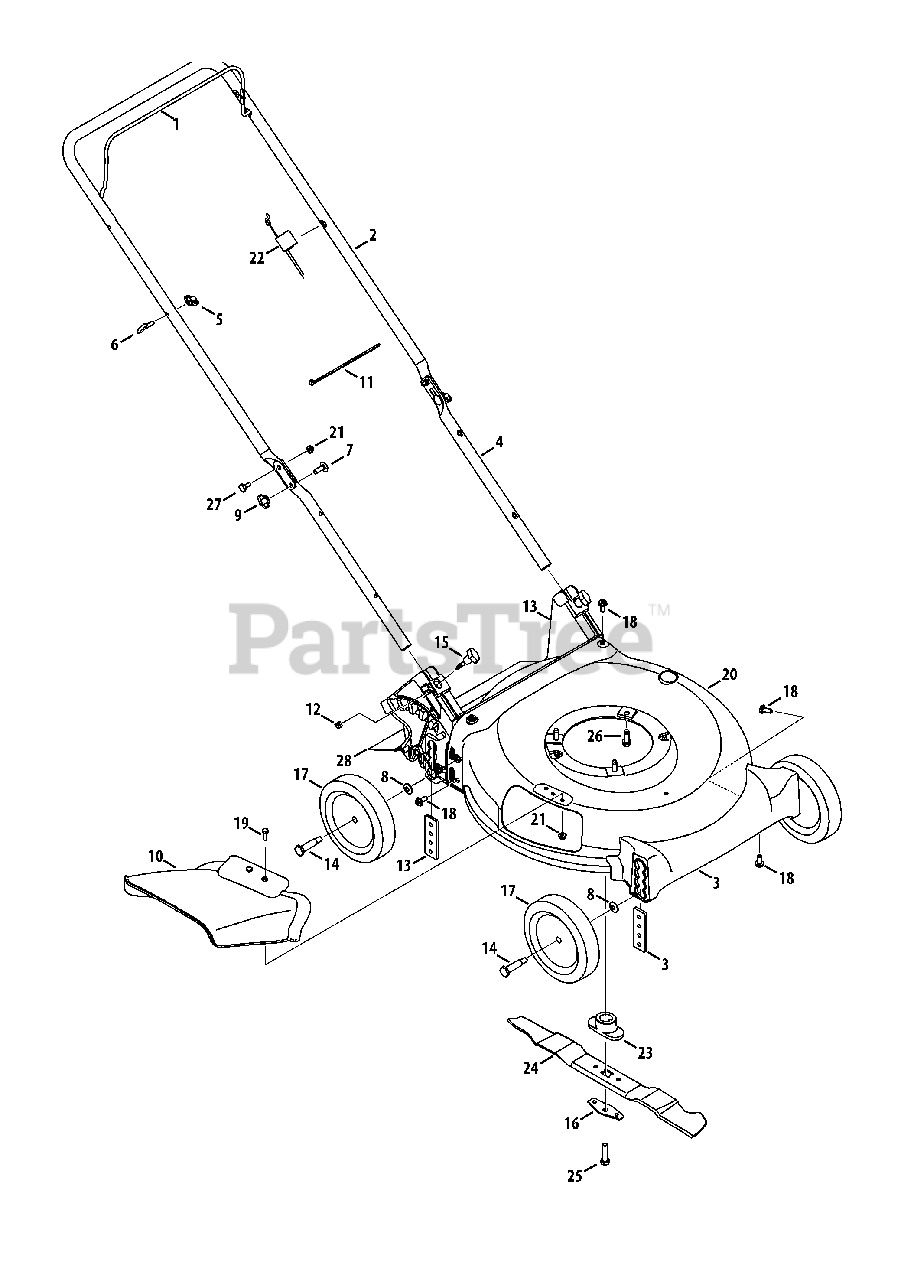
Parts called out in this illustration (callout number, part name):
1	Blade Control
2	Upper Handle
3	Front Cover Assembly
4	Lower Handle
5	Wing Nut
6	Rope Guide
7	Carriage Screw ,5/16-18
8	Washer, .401 x .870 x .060
9	Wing Knob
10	Side Chute
11	Cable Tie
12	Nut, Sq., 1/4-20
13	Rear Baffle
14	Shoulder Screw
15	Wing Nut
16	Blade Bell Support
17	Wheel, 7" Star-Dia., Oys. Gray
18	Screw, 5/16-14 x .750
19	Screw, 1/4-20 x .750
20	Deck , 21"
21	Nut, Flange Lock, 1/4-20
22	Control Cable
23	Blade Adapter
24	Mulching Blade
25	Screw , 3/8-24 x 1.50
26	TT Sems Screw, 3/8-16 x 1.0
27	Sldr. Screw, .375 x .126 x 1/4-20
28	Trail shield
